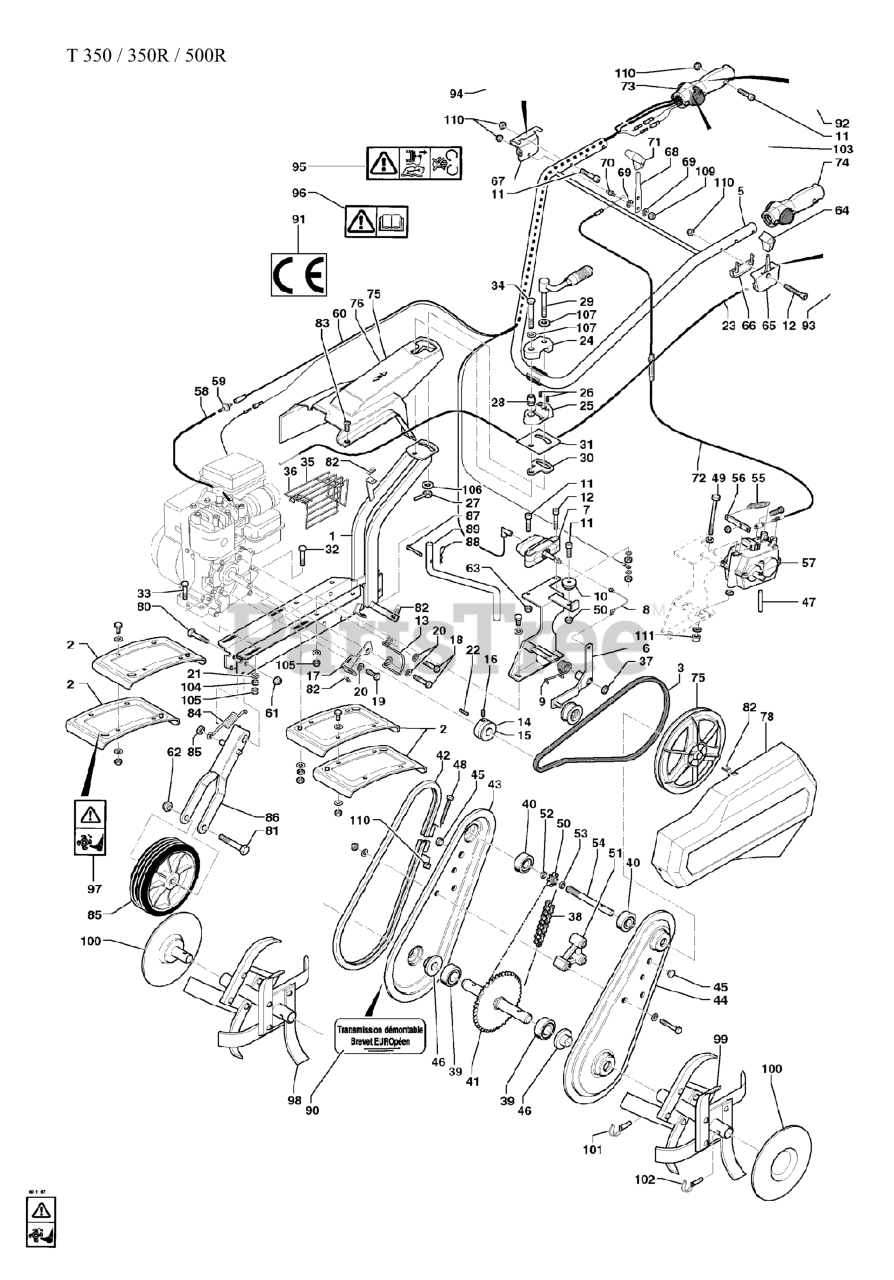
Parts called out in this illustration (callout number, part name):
20	WASHER - 15X7.3X1.6
38	DRIVE CHAIN
46	SPACER SLEEVE
65	THROTTLE TRIGGER
66	THROTTLE CONTROL
82	NUT
85	WHEEL
88	COTTER PIN
106	WASHER
110	Blocking nut M 6 Z
